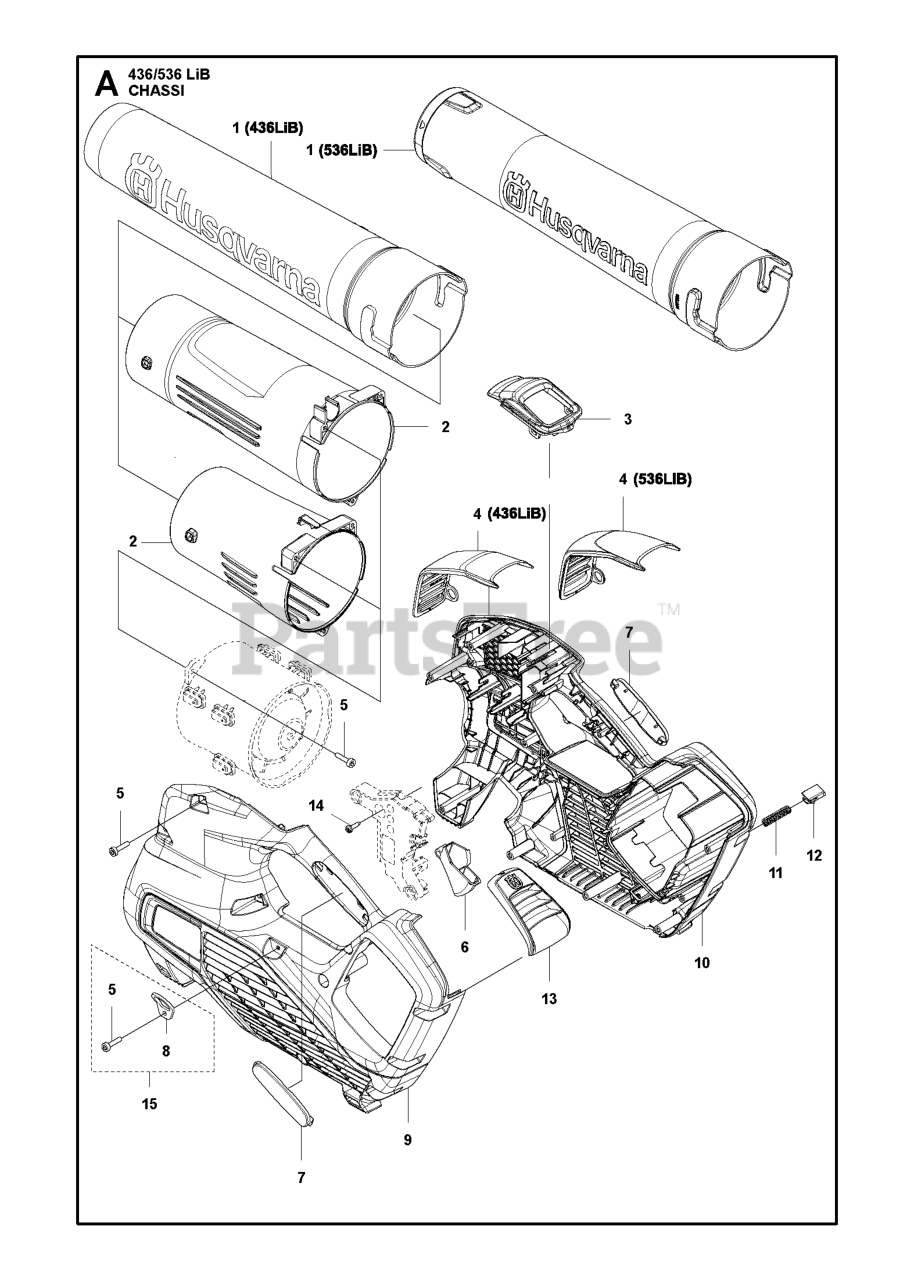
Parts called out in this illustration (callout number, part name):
1	NOZZLE 436LIB
1	NOZZLE BLOWER 320IB
1	TUBE ASSY
1	TUBE ASSY NOZZLE 536LIBX
2	TUBE FAN OUTLET
2	TUBE FAN SYSTEM
3	FRAME KEYPAD
4	COVER
5	SCREW
6	THROTTLE CONTROL
7	HANDLE INSERT GREY
9	HOUSING LEFT
10	HOUSING RIGHT
11	SPRING PUSH OUT
12	PUSH BUTTON
15	KIT EYELET
